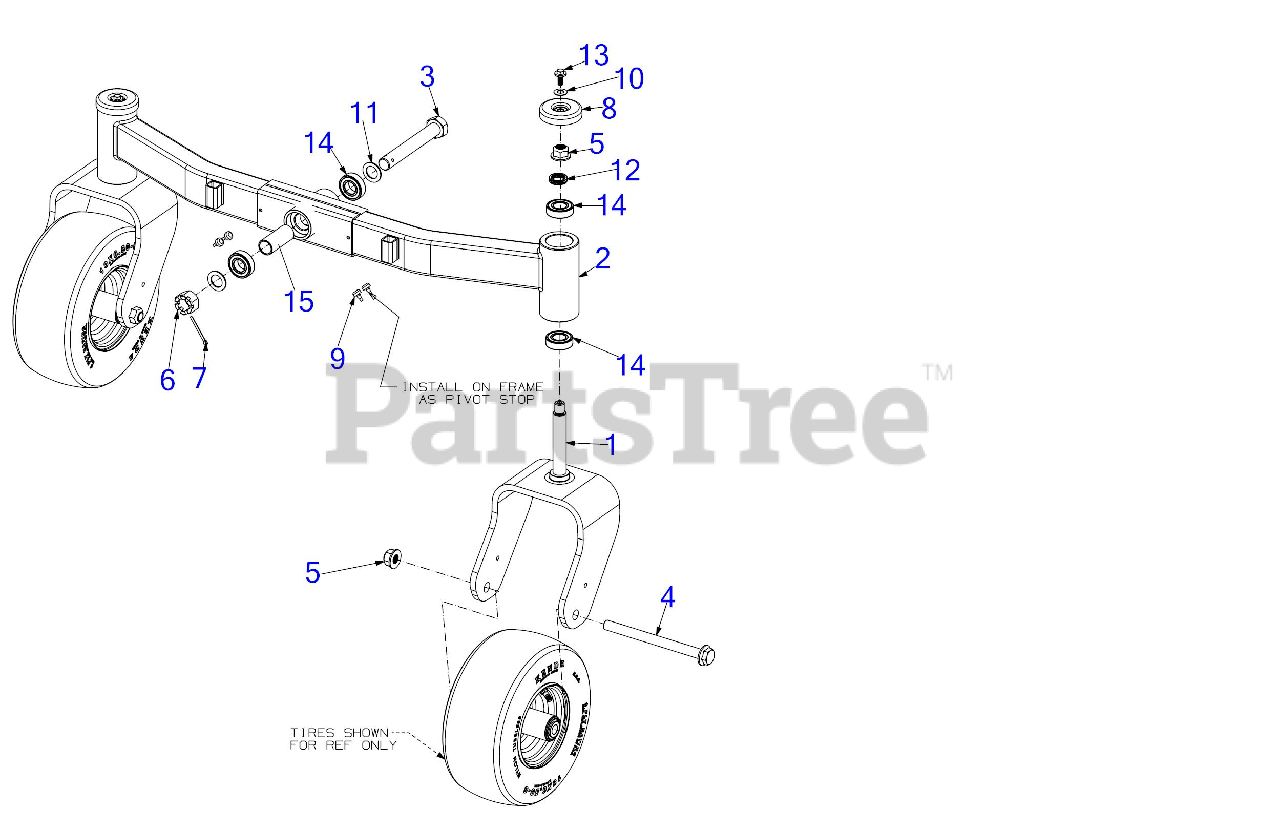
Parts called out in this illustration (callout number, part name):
3	SCREW 1-14:7.0 GR5
4	SCREW 3/4-16 x 9.00 GR5
5	FLANGE LOCK NUT 3/4-16 TOP LOCK
6	CASTLE NUT 1.0-14 GR5
7	COTTER PIN
8	AXLE CAP 3"
9	BUMPER, .62 DIA x .3
10	BELL WASHER
11	FLAT WASHER 1.031 X1.62 X.095
12	WAVE WASHER
14	BALL BEARING 1.0 x 52 x 15
15	SPACER 1.00 X 1.25 X 2.99
